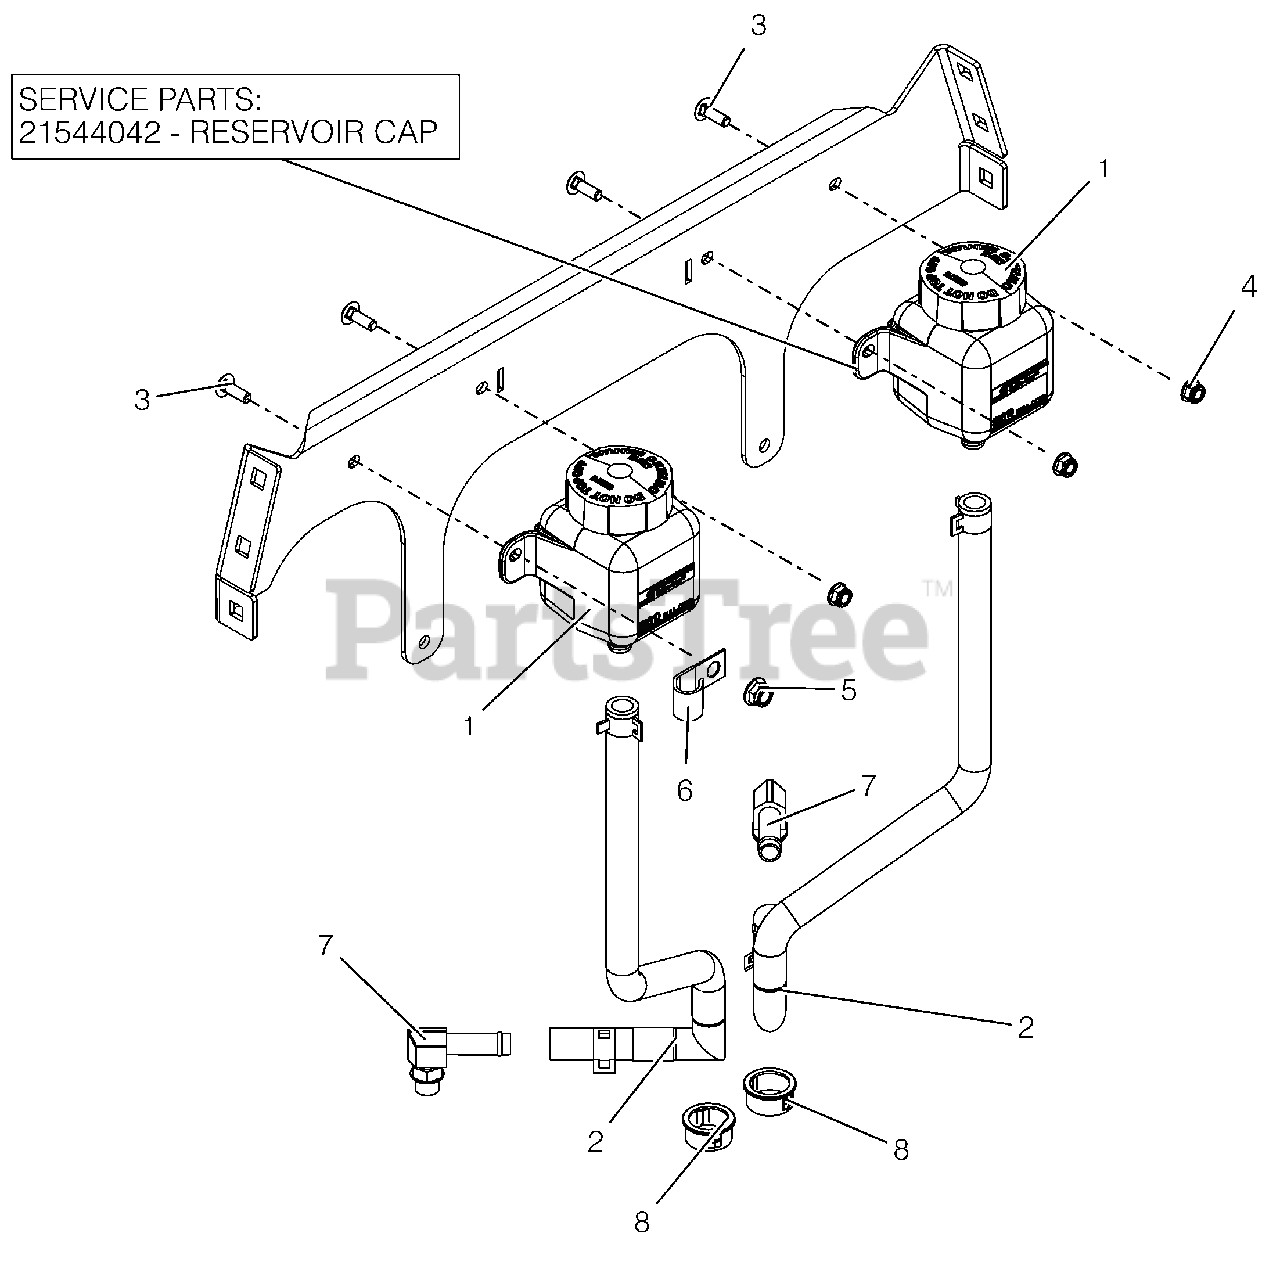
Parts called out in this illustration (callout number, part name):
1	TANK, EXPANSION
1	CAP, HYDRO RESERVOIR REPLAC.
2	HYDRO, SYSTEM PRO-STANCE
3	@BLT-RDHDSQNK .25-20X.75 G5YZ
4	@NUT-LK-NYL-FLG .25-20 YWZC
5	@NUT-LK-NYL-FLG .31-18 YWZC
7	FITTING, HYD (90 DEG)
8	BSHG, PANEL SNAP .937X1.11X.56
